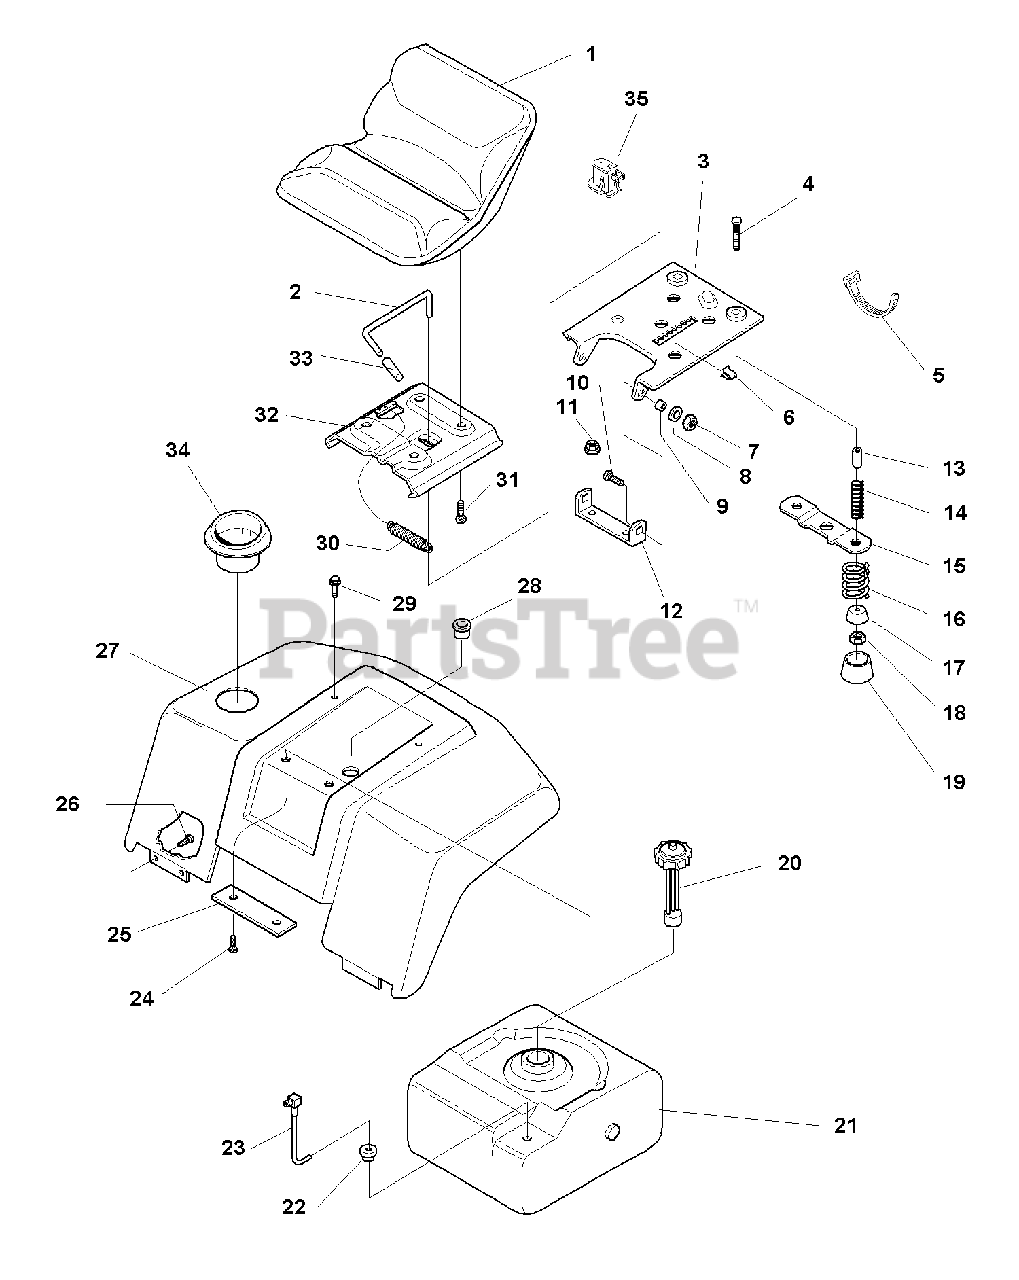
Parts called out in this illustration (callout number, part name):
1	SEAT, High-Back
2	LEVER, Seat Release
3	SUPPORT, Seat Pivot
4	CARRIAGE BOLT, 5/16-18 x 2
5	TIE, Self-locking, 15"long
6	CLIP, Speed
7	NUT, Hex Nylon Lock, 3/8-16
8	WASHER, Plain, 13/32
10	CARRIAGE BOLT, 3/8-16 x 1
11	NUT, Hex Flange, 3/8-16
12	BRACKET, Seat Pivot
14	SPRING, Compression
15	PLATE, Switch
16	SPRING, Compression
17	WASHER, Plain
18	NUT, Hex Nylon Lock, 5/16-18
19	COVER, Spring
20	CAP, Fuel Gauge
21	TANK, Fuel
23	ELBOW & TUBE ASSEMBLY
24	CAPSCREW, Truss Head, Torx Drive, 3/8-16 x 1
25	PLATE, Reinforcement
26	CAPSCREW, Taptite, 1/4-20 x 1/2
27	SEAT DECK, Orange
27	SEAT DECK, Red
28	BUSHING, Snap
29	CAPSCREW, Taptite, 5/16-18 x 5/8
30	SPRING, Extension
31	CAPSCREW, Hex, Whizlock, 5/16-18 x 5/8
32	BRACKET, Seat Slide
33	HANDLE, Grip
35	SEAT SWITCH
